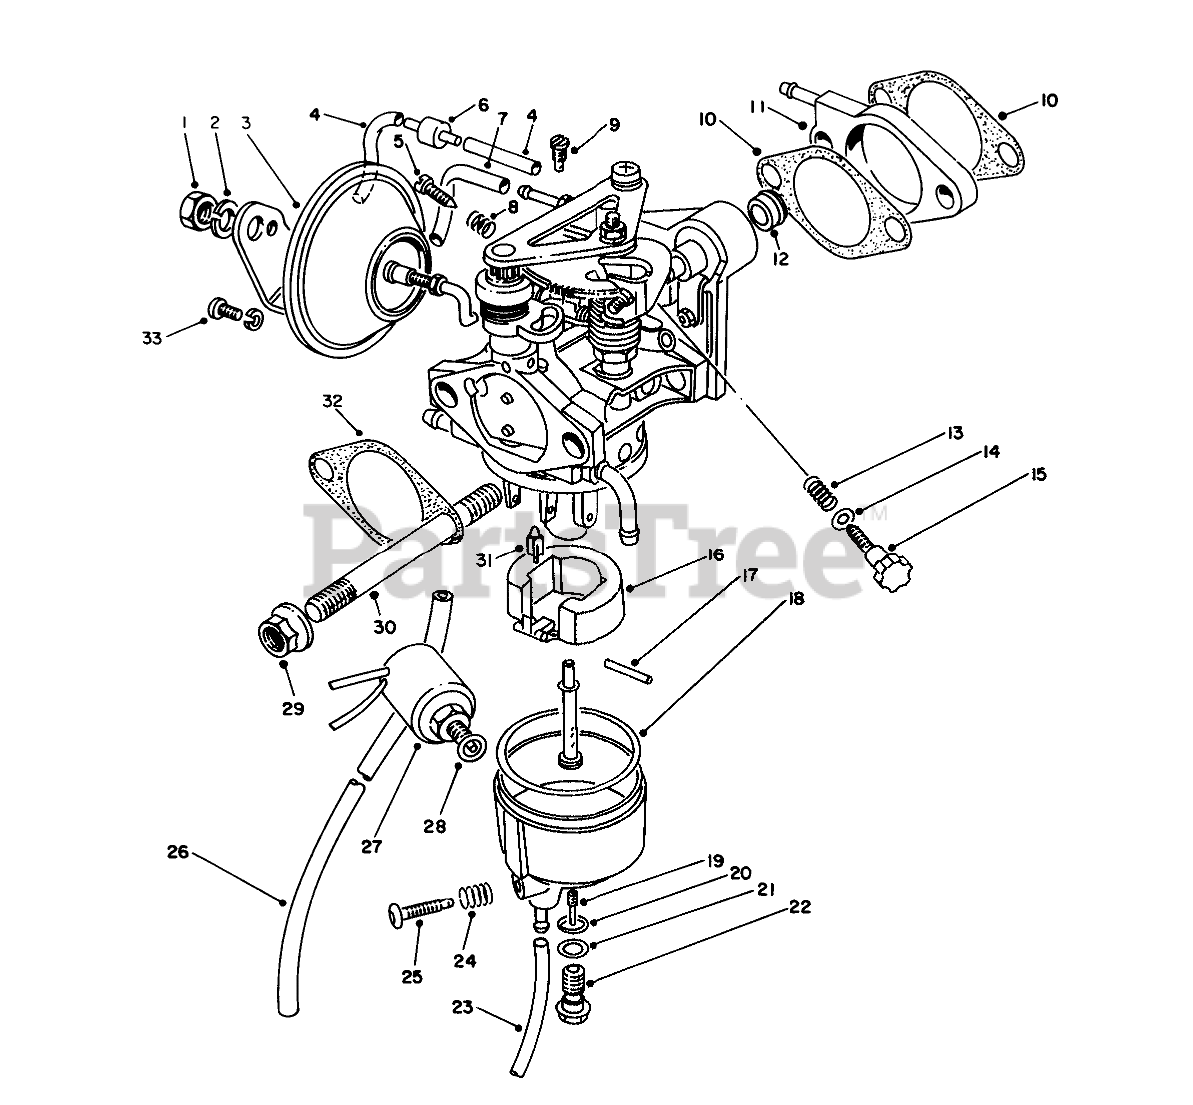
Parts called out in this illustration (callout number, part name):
2	WASHER-LOCK
3	Depression Chamber
5	Screw
6	Valve-Delay
8	SPRING
9	PILOT JET (65)
10	Gasket-Carburetor (ID:27)
11	Insulator-Carburetor
12	Cover (W:3.5)
13	SPRING
14	WASHER (4.2X8X0.5)
15	Screw-Idle Adjusting
16	Float
17	Pin
18	Gasket
19	Jet-Main (105)
20	0-Ring
21	Washer
22	Holder
24	Spring
25	Screw
27	Solenoid
28	Washer
30	Stud Bolt
31	Needle
32	Gasket
33	SCREW
